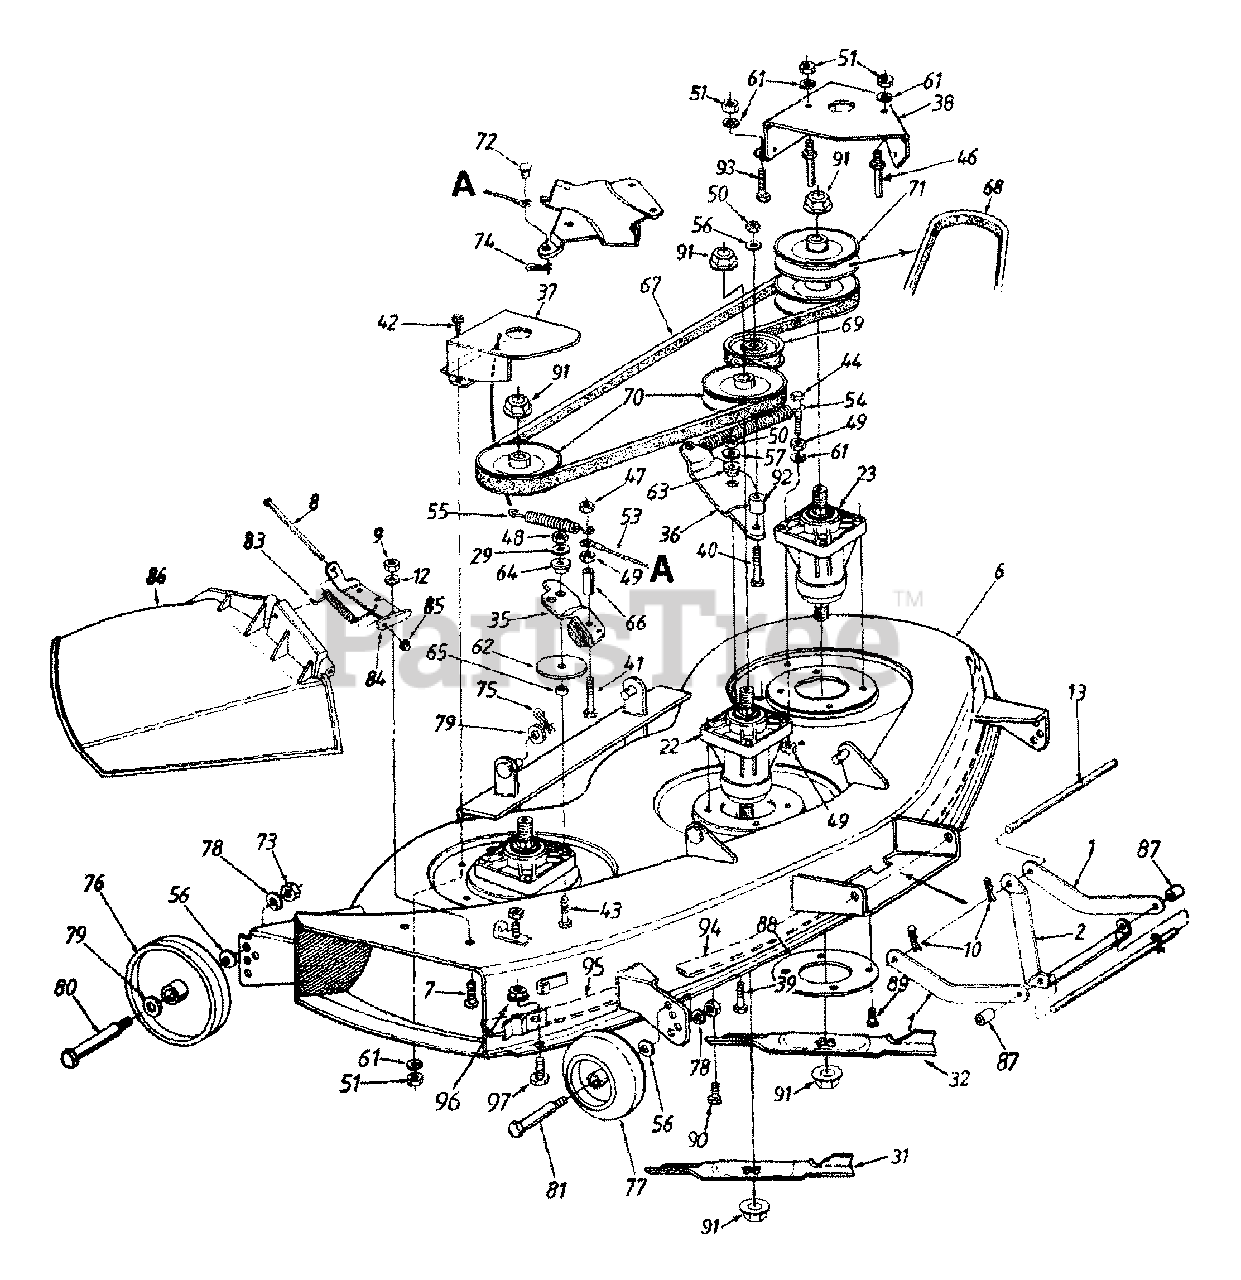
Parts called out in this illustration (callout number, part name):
8	Hinge Pin
9	Hex Nut 1/4-20 Thd. (Gr. 5)
10	Hairpin Clip
12	Bell-Wash. 1/4" I.D.
13	Deck Connecting Rod
22	Spindle Ass'y. (R.H. & Center)
23	Spindle Ass'y. (L.H.)
29	Lock Wash. 5/16" I.D.
31	Blade 14.88" Lg. (Middle)
32	Blade 16.28" Lg. (R.H. & L.H.)
35	Deck Brake Brkt. Ass'y.
36	Idler Bracket
39	Hex Bolt 3/8-24 x 1.0" Lg.
40	Hex Bolt 3/8-24 x 2" Lg.
41	Hex Bolt 1/4-28 x 1.75" Lg.
42	Hex Wash. Hd. Tap-Scr. 1/4-20 x .5" Lg.
43	Hex Bolt 5/16-24 x 1.5" Lg. (Grade 5)
44	Hex Bolt 1/4-28 x 1.5" Lg.
46	Belt Guard Pin 1/4" Dia.
47	Hex Cent. L-Nut 1/4-28 Thd.
48	Hex Nut 5/16-24 Thd.
49	Hex Nut 1/4-28 Thd.
50	Hex Nut 3/8-24 Thd.
51	Hex Nut 1/4-20 Thd. (Gr. 5)
53	Brake Cable Ass'y.
54	Extension Spring 6.17" Lg.
55	Extension Spring 3.97" Lg.
56	Bell-Wash. .38" I.D. x .88" O.D.
57	Bell-Wash. .39" I.D. x 1.13" O.D.
61	L-Wash. 1/4" I.D.
62	Fl-Wash. 5/16" I.D. x 3" O.D.
63	Shld. Spacer .625" I.D.
64	Shld. Spacer
65	Spacer .34" I.D.
66	Spacer .326" I.D.
67	V-Belt
68	V-Belt
69	Fl-Idler Pulley 3.5" O.D.
70	Pulley 5.0" Dia.
71	Double Pulley 5.0" Dia.
72	Clevis Pin 1/4" Dia. x .53" Lg.
73	Hex Nut 3/8-16 Thd.
74	Intern. Cotter Pin 5/16" Dia.
75	Intern. Cotter Pin 3/8 Dia.
76	Deck Wheel 5" Dia.
77	Deck Wheel w/Insert 5" Dia.
78	L-Wash. 3/8" I.D.
79	Fl-Wash. .531" I.D.
80	Shoulder Bolt .498" Dia. x 1.64" Lg.
81	Shoulder Bolt
83	Torsion Spring
84	Hinge Mtg. Brkt.
85	Push Nut
86	Chute Ass'y.
87	Spacer 5/8" I.D. x 7/8" O.D.
90	Hex Wash. Hd. Scr. 5/16-18 x .75" Lg.
91	Hex Flange Nut 5/8-18 Thd.
92	Spacer .38" I.D.
93	Hex Bolt 1/4-20 x .5" Lg.
96	Hex Sems Nut 1/4-20 Thd.
97	Carriage Bolt 1/4-20 x .5" Lg.
